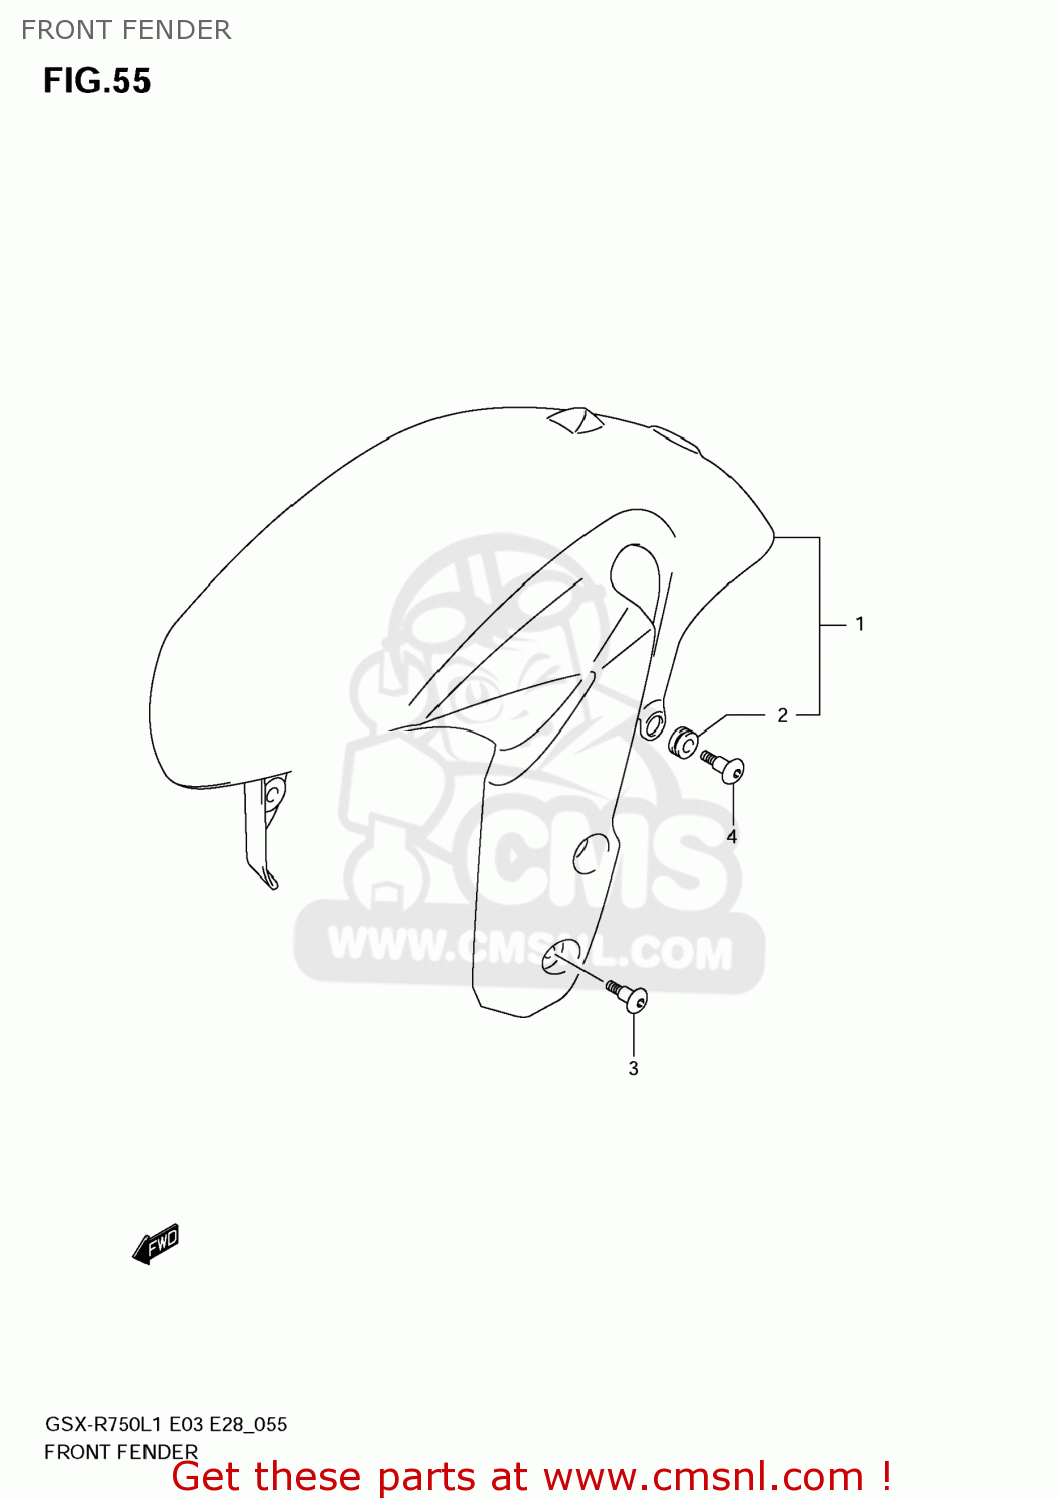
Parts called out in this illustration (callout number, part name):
1	FENDER ASSY,FR(WHITE)
2	CUSHION
3	SCREW(6X16)
4	SCREW(6X16)
